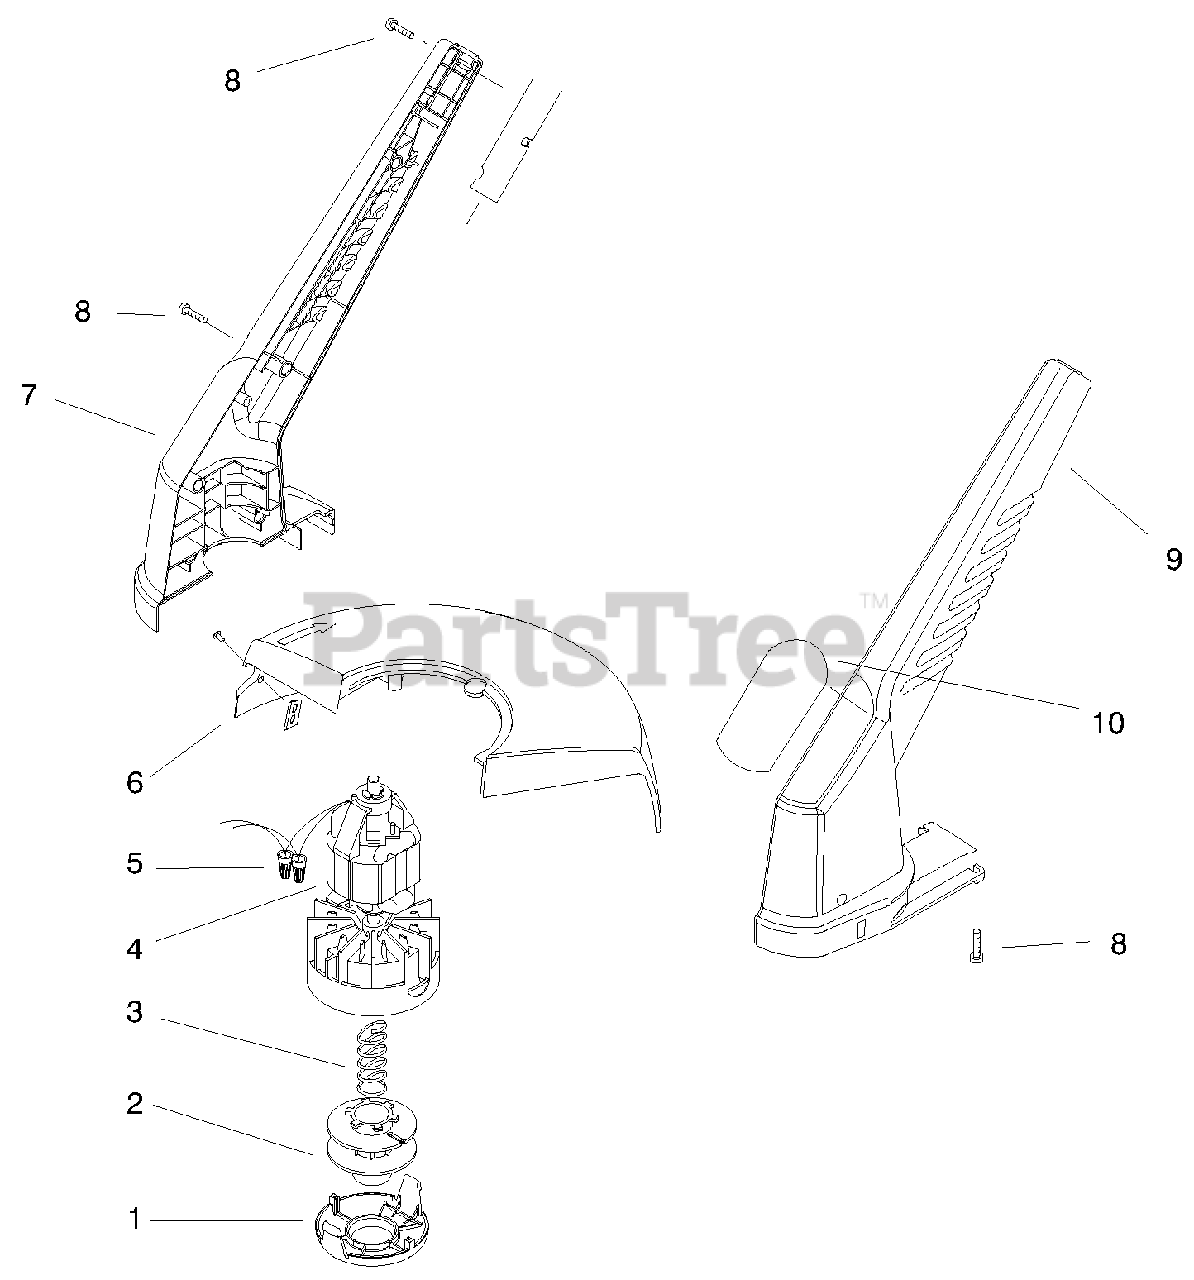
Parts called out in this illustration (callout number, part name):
4	Motor Assembly
5	Connector-Wire Nut
6	ASM-Shield
7	Housing R.H.
8	Screw-Pan Hd.
9	Housing L.H.
10	Decal-13" Trimmer
